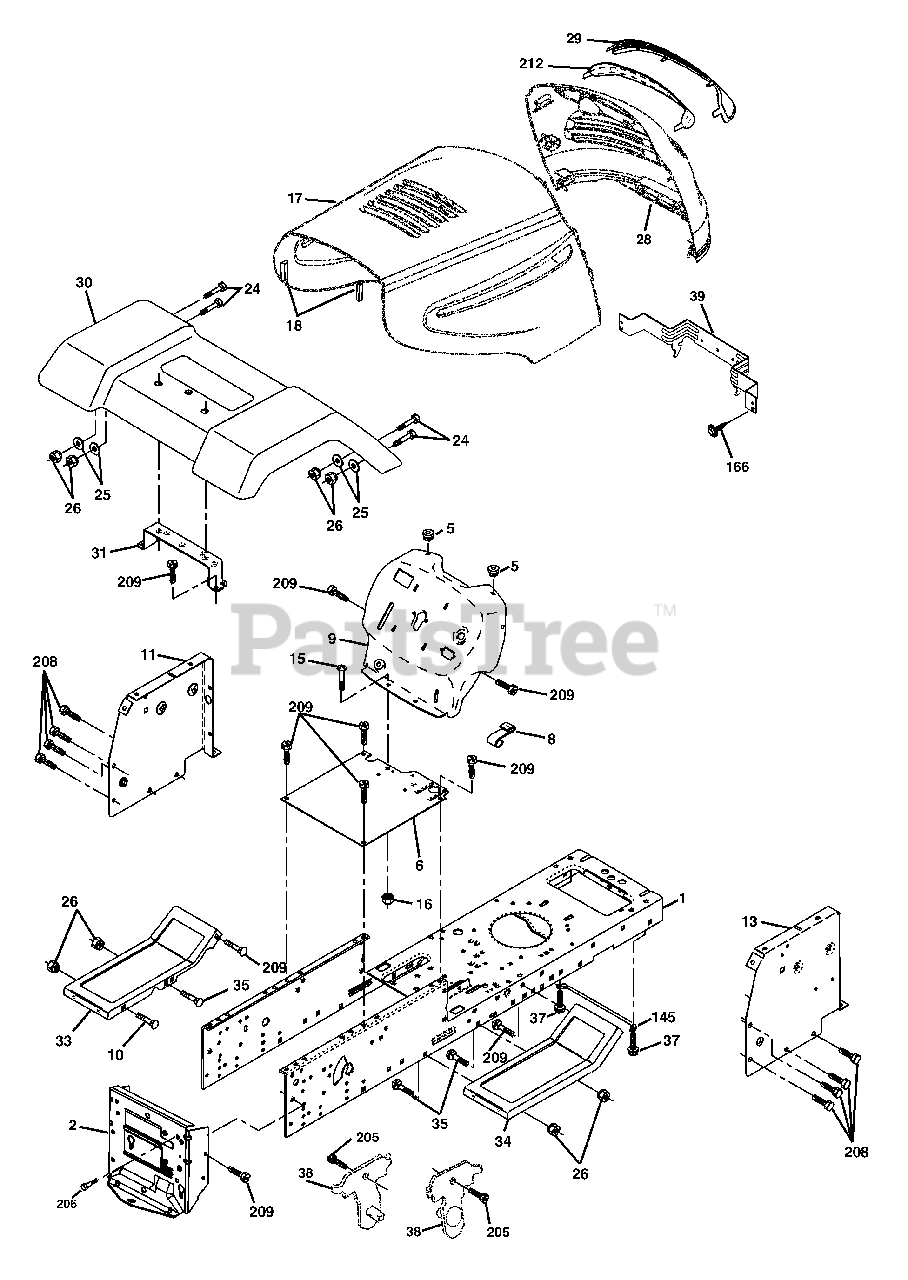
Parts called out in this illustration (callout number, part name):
1	Chassis
2	Drawbar, Stretch
5	Bumper, Hood/Dash
6	Saddle Silkscreen
8	Clip Retainer Slide-On
9	Dash
10	Bolt, Carriage 3/8-16 x 1
11	Panel Dash LH
13	Panel Slkscr Dash RH
15	Screw Mach TRHD 5/16-18 unc x 3/4
16	Nut Keps 5/16-18 unc
17	Hood
18	Bumper Hood
24	Bolt Fin Hex 3/8-16 unc x 1 Gr. 5
25	Washer 13/32 x 13/16 x 12 Ga.
26	Nut Lock Hex w/Ins 3/8-16 unc
28	Grille/Lens Asm.
29	Lens Grille Basic Bar
30	Fender
31	Bracket Fender Repl 109873X
33	Footrest Pnt LH
34	Footrest Pnt RH
35	Bolt Rdhd Sht Sqnk 3/8-16 x 3/4
37	Screw Thdrol 5/16-18 x 1/2 TYT
38	Bracket Asm. Pivot Mower
39	Bracket Pivot
145	Rod Pivot Chassis/Hood
166	Screw Hwhd Hi-Lo #13-16 x 5/8
205	Screw Thdrol 3/8-16 x 1/2
206	Bolt Shoulder 5/16-18
208	Screw Thdrol 3/8-16 x 1/2
209	Screw Hex Wsh Thdrol 3/8-16
212	Insert Lens Reflect
